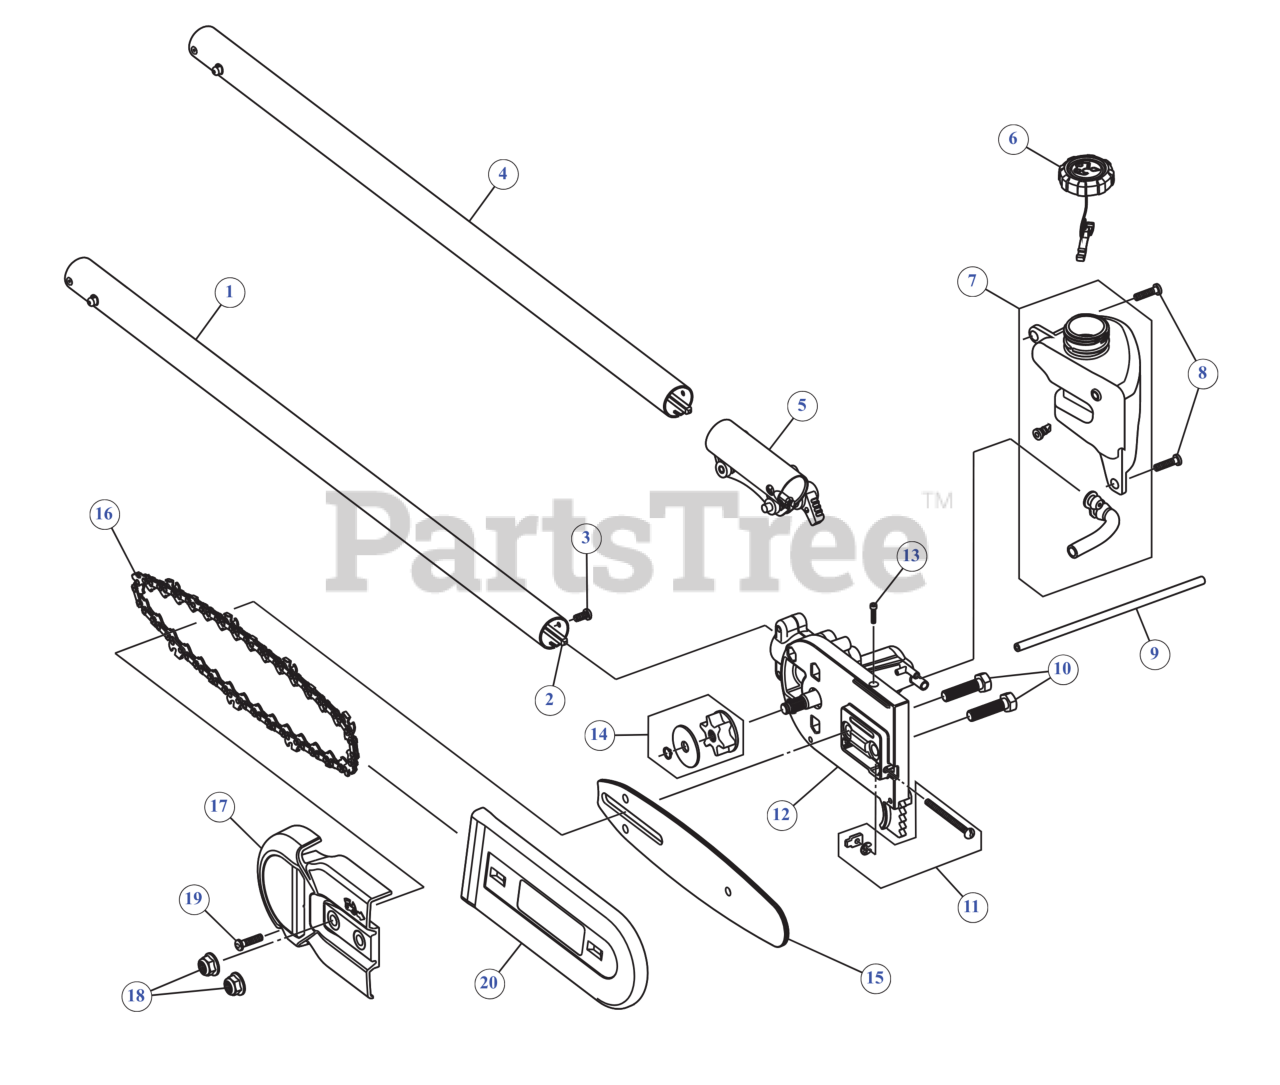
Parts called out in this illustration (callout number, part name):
1	LOWER DRIVE SHAFT HOUSING
2	FLEXIBLE DRIVE SHAFT
3	SCREW 1/4-20 X.500
4	BOOM ASSEMBLY
5	CLAMP ASM DW BK
6	OIL CAP
7	OIL TANK
8	SCREW, #8-16X.750 PH
9	OIL LINE
10	SCREW 5/16-18 x 1.25 GR5
11	CHAIN TENSION HDW
12	GEAR BOX ASSEMBLY
13	SCREW 4X40X.50
14	SPROCKET ASSEMBLY
15	BAR 8" SPROCKET NOSE
16	CHAIN 8" 34 LINK .043 GAUGE
17	CHAIN GUARD
18	FLANGE LOCK NUT 5/16-18
19	SCREW, #8-16X.750 PH
20	8" SCABBARD
